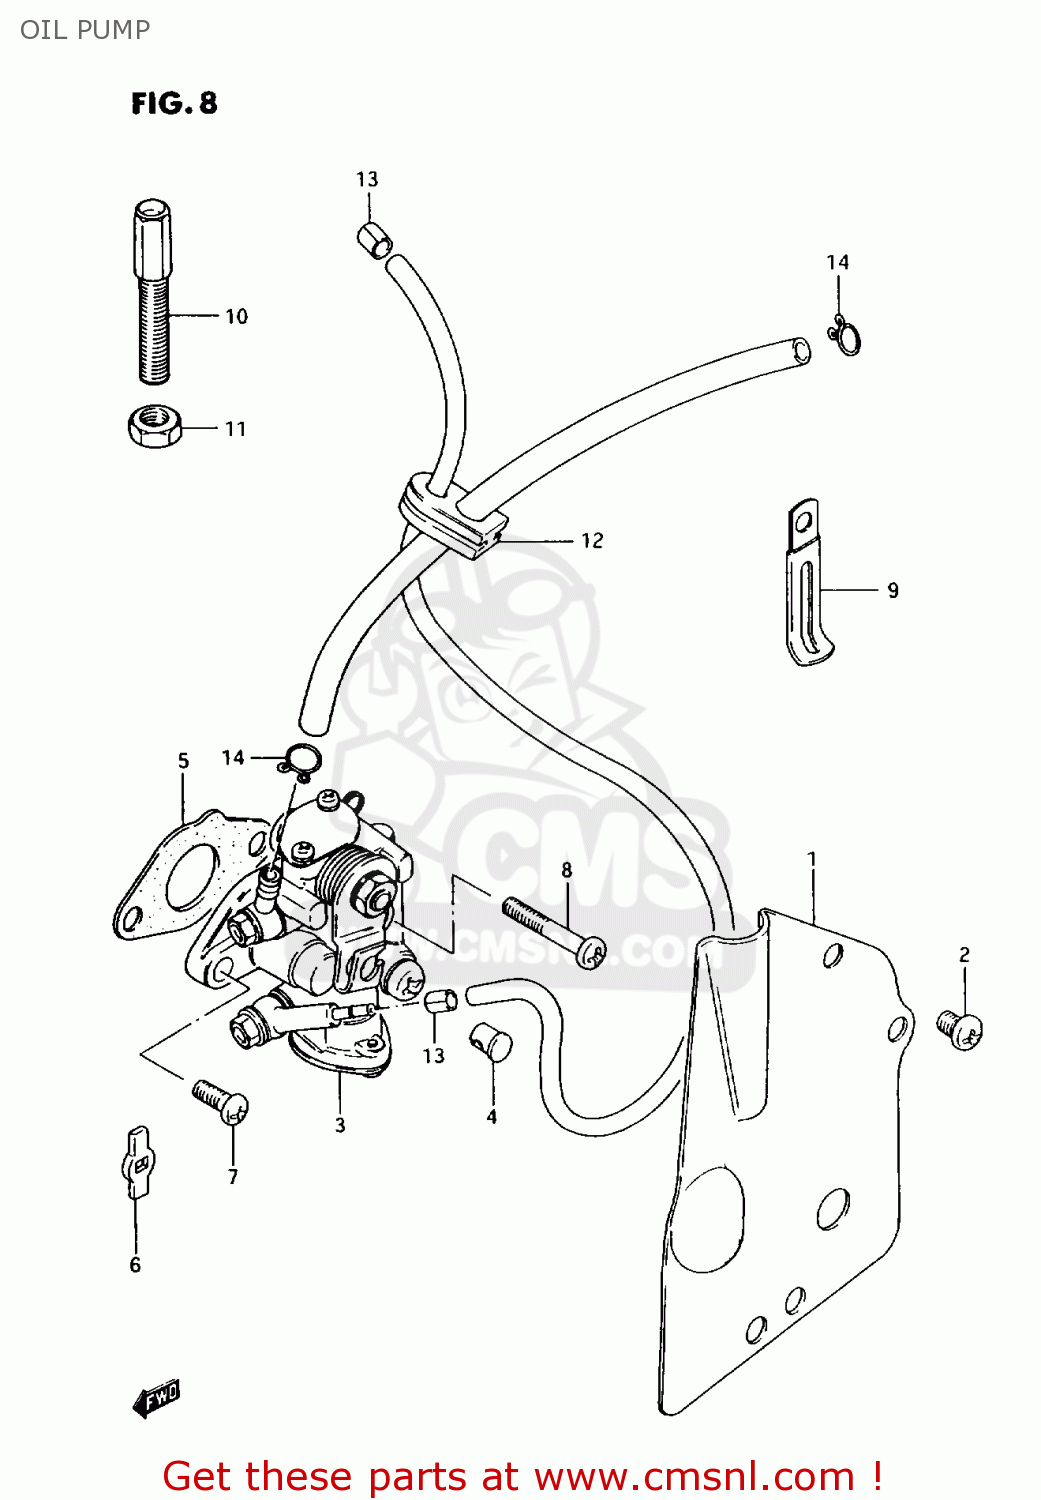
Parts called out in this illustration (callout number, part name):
1	CAP,OIL PUMP INSPECTION
2	SCREW
3	PUMP ASSY,OIL
4	TERMINAL,CABLE
5	GASKET,OIL PUMP (NAS)
6	PIECE,OIL PUMP DRIVE
7	SCREW
8	SCREW
9	CLAMP
10	BOLT
11	NUT
12	HOSE,OIL
13	CLIP
14	CLIP
